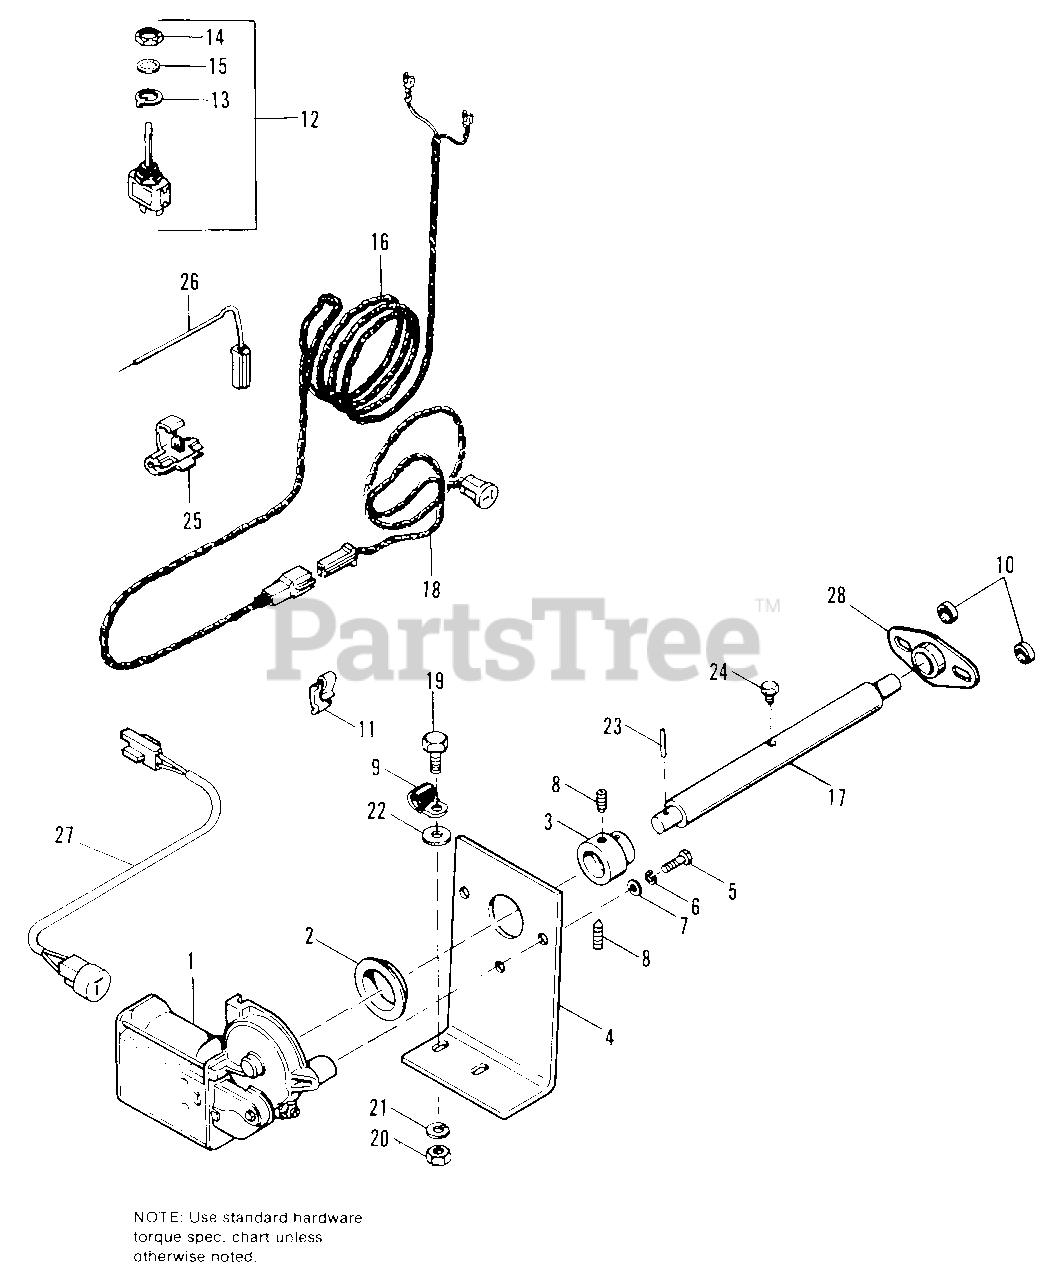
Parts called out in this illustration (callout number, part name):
1	SPOUT CONTROL, Motor
2	BEARING, Flange
4	BRACKET, Motor
5	CAPSCREW, Hex Hd, 1/4-20 x 3/4
6	LOCKWASHER, Spring, 1/4
7	WASHER, Plain, 1/4
8	SCREW, Hex, Skt Hd, #10-24 x 3/8
12	SWITCH, Spout Control
13	RING, Locking
15	LOCKWASHER, Int
16	HARNESS ASSY, Switch
17	ROD, Spout Control
18	HARNESS, Wiring
19	CAPSCREW, Hex Hd, 3/8-16 x 1
20	NUT, Hex, 3/8-16
21	LOCKWASHER, Spring, 3/8
22	WASHER, Plain, 5/16
23	PIN, Spring, 5/32 x 1
24	SCREW, Hex, Wash. Hd, Taptite, 1/4-20 x 3/8
26	WIRE ASSY
27	ADAPTOR, Harness
